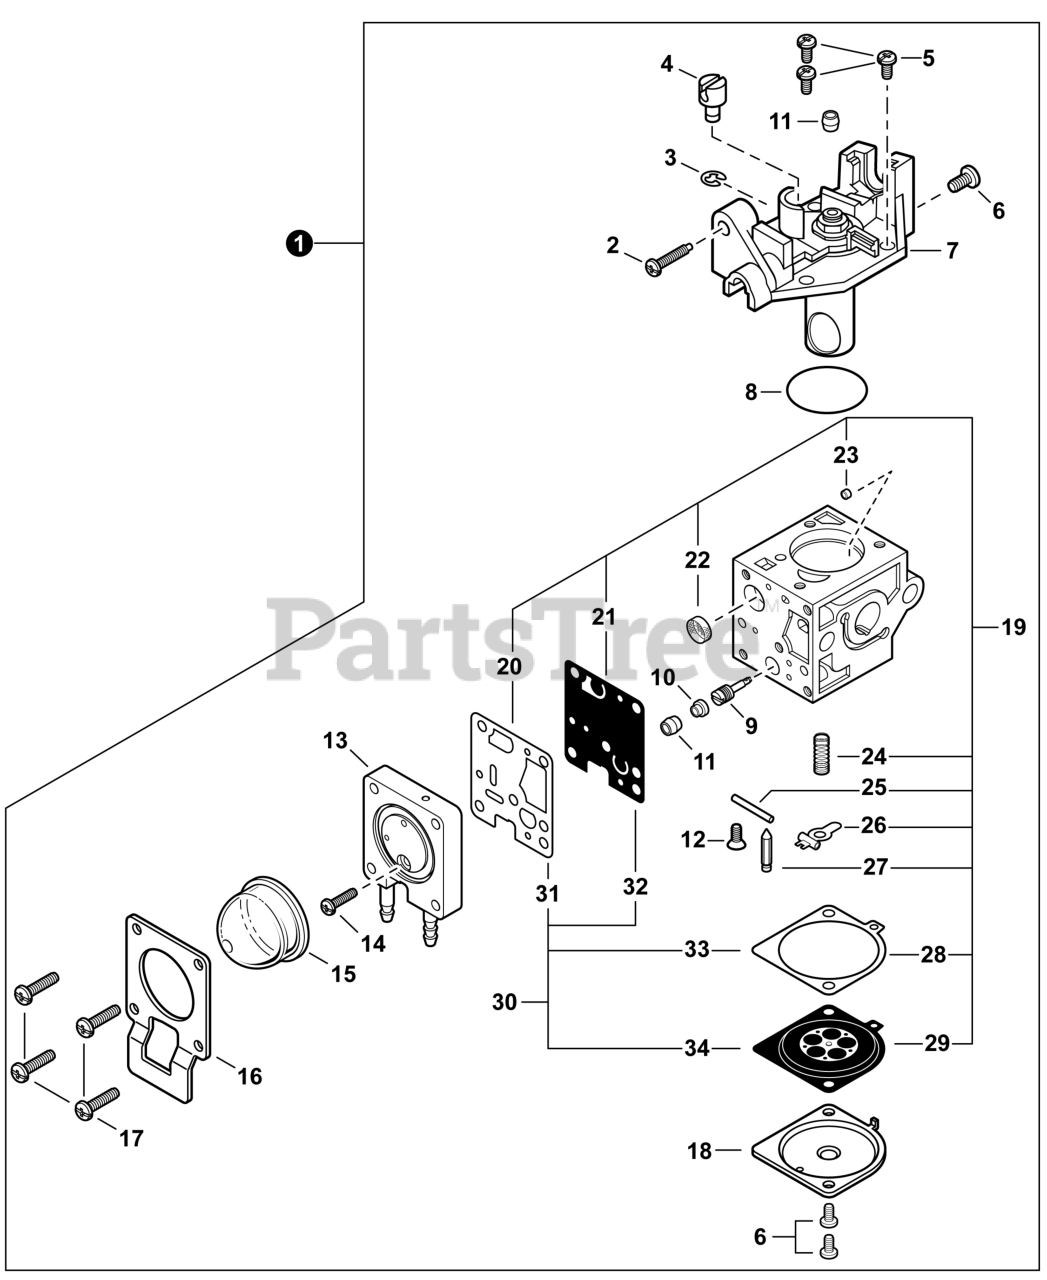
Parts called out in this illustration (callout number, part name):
1	CARBURETOR RB-110128D
2	SCREW, IDLE ADJUST
7	COVER ASSY, ROTOR
9	NEEDLE, MIXTURE
10	CAP, LIMITER
13	BODY ASSY, PURGE
15	BULB, PURGE
16	RETAINER, PURGE BULB
18	COVER, METERING DIAPHRAGM
19	REPAIR KIT, CARBURETOR
20	GASKET, PUMP
21	DIAPHRAGM, PUMP
22	SCREEN, FUEL INLET
23	GUIDE, ROLLER
24	SPRING, METERING LEVER
25	PIN, METERING LEVER
26	LEVER, METERING
27	VALVE, INLET NEEDLE
28	GASKET, METERING DIAPHRAGM
29	DIAPHRAGM, METERING
30	GASKET / DIAPHRAGM KIT
31	GASKET, PUMP
32	DIAPHRAGM, PUMP
33	GASKET, METERING DIAPHRAGM
34	DIAPHRAGM, METERING
